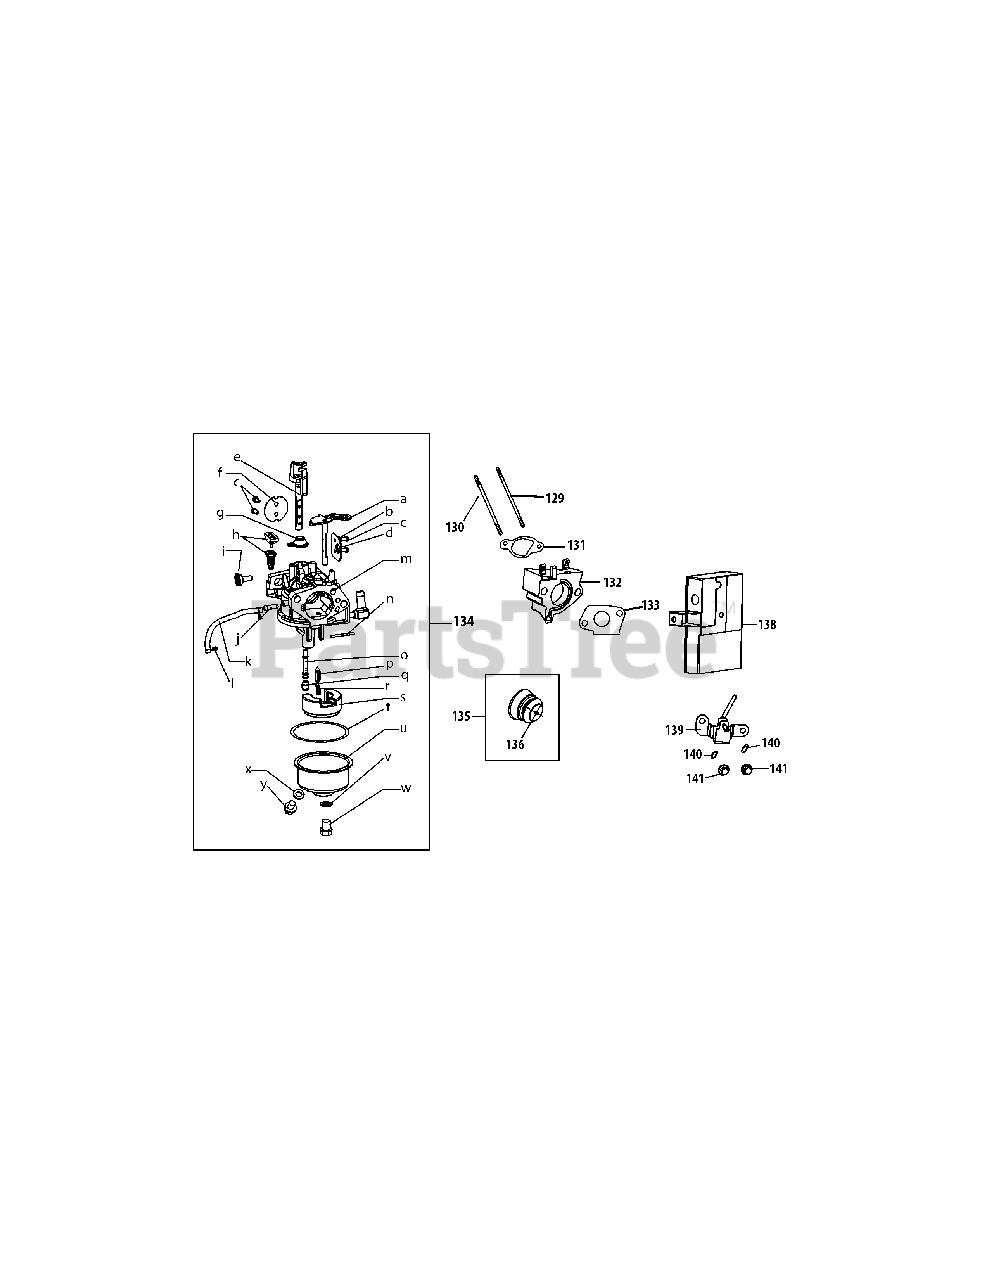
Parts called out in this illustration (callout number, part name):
129	Stud M6-8×100 Carburetor
130	Stud M6-8×118 Carburetor
131	Carburetor Insulator Gasket
132	Carburetor Insulator
133	Carburetor Gasket
134	Carburetor Assembly
135	Primer Assembly
138	Heater Box
139	Choke Control
140	Lock Washer
141	Nut M6
